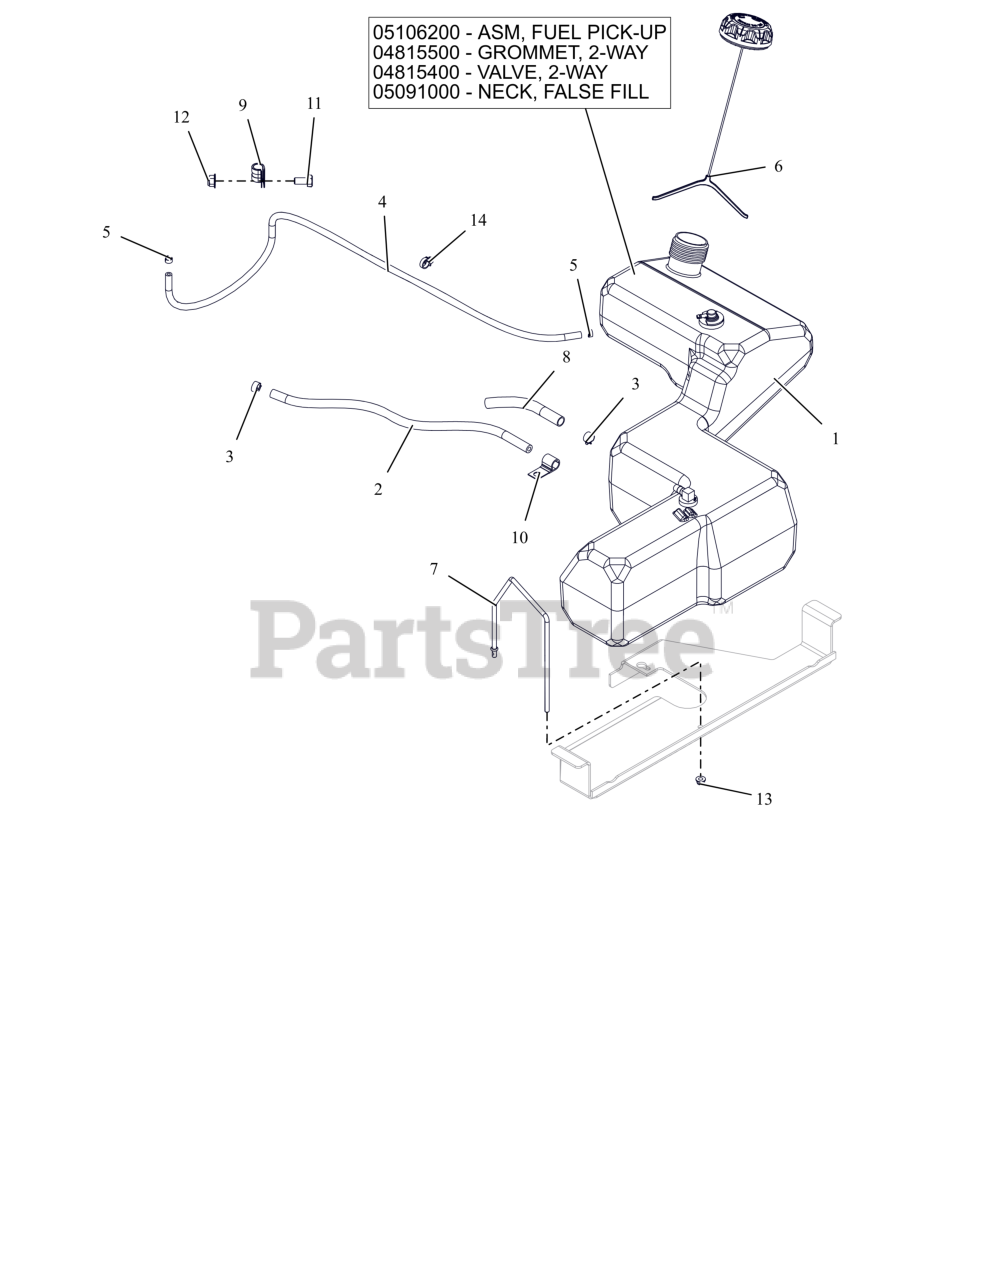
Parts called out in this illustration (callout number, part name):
1	ASM, FUEL TANK-IKON
1	ASM, IKON FUEL PICK-UP
1	GROMMET, 2-WAY
1	VALVE, 2-WAY
1	NECK, FALSE FILL-2017 IKON
2	HOSE, .25 LOW-PERM BULK GAS
3	CLAMP, FUEL LINE
4	HOSE, .188 LOW-PERM BULK GAS
5	CLAMP-HOSE, SPRING .188
6	CAP, FUEL VENT-IN 2.25" RATCH.
7	BRKT, FUEL TANK HOLD DOWN
8	WRAP, ANTIABRASION .5X.064WALL
9	CLAMP, CUSHIONED STEEL
10	J-CLAMP
11	BLT,HEX .38-16X.75 G5 ZCC
12	NUT,NYL-FLG .38-16 GF ZCC
13	NUT,NYL-FLG .25-20 GF ZCC
14	ROUTING CLIP (1/2" ID)
